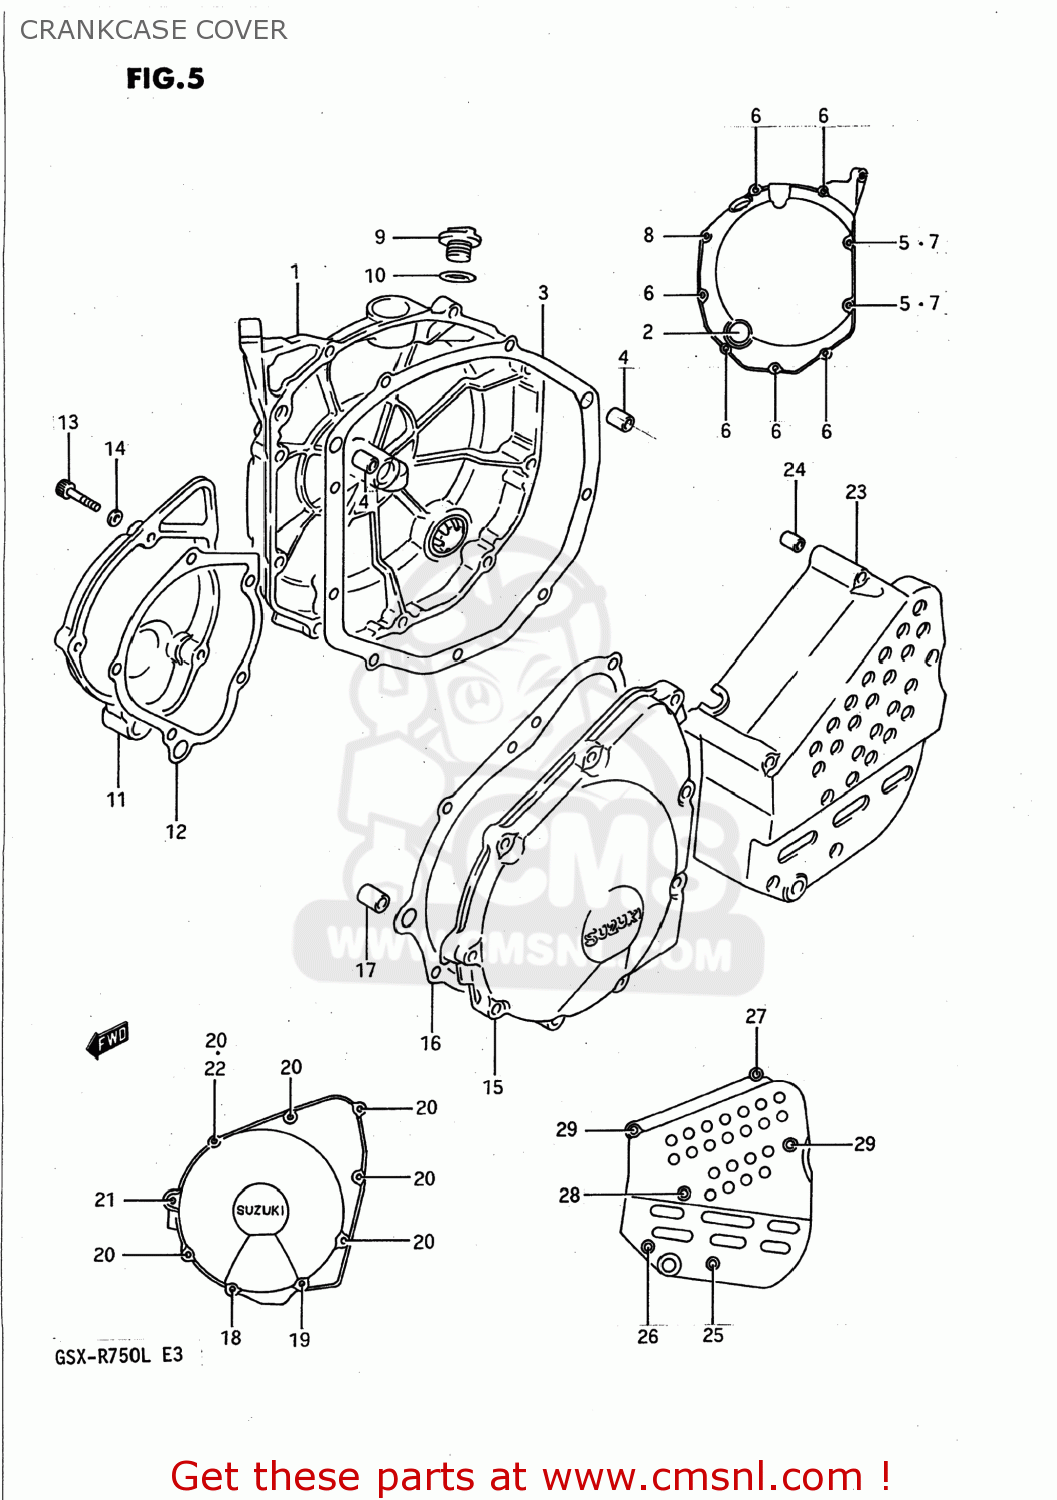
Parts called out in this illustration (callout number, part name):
1	COVER,CLUTCH
2	LENS,OIL LEVEL CHECK
3	GASKET,CLUTCH COVER (MCA)
4	PIN
5	GASKET(5.8X11X1.2) (NAS)
6	BOLT
7	BOLT
8	BOLT
9	PLUG
10	O RING(D:3.1,ID:16.8)
11	COVER,SIGNAL GENERATOR
12	GASKET,SIGNAL GENERATOR COVER (NAS)
13	BOLT
14	GASKET(5.8X11X1.2) (NAS)
15	COVER,STARTER GEAR
16	GASKET,STARTER GEAR COVER (NAS)
17	PIN (11X20)(SUS)
18	BOLT
19	BOLT
20	BOLT
21	BOLT
22	GASKET(5.8X11X1.2) (NAS)
23	COVER,SPROCKET
24	PIN
25	BOLT
26	BOLT
27	BOLT
28	BOLT
29	BOLT
